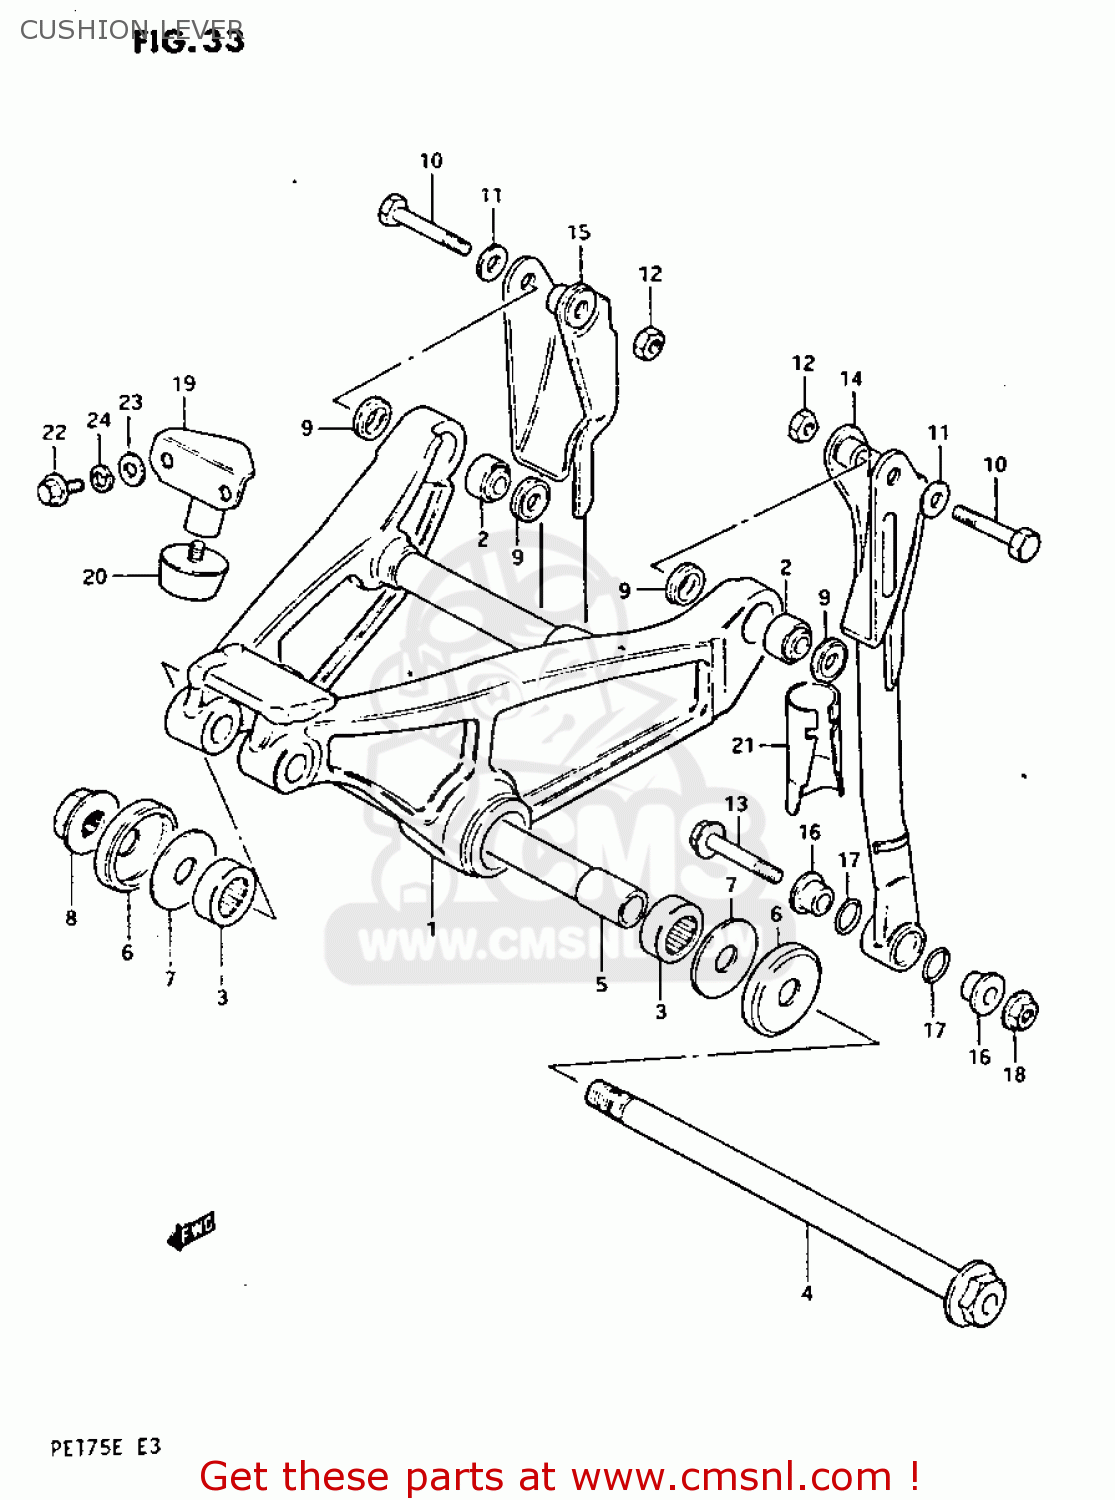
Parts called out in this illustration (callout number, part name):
1	LEVER SET,REAR CUSHION
2	BEARING(8X18X11)
3	BEARING(17X26X20)
4	SHAFT,REAR CUSHION LEVER
5	SPACER,REAR CUSHION LEVER
6	DUST SEAL,REAR CUSHION,LEFT
7	WASHER
8	NUT 12MM
9	DUST SEAL,RR CUSHION LOD UPR.
10	BOLT 8X38
11	WASHER
12	NUT
13	BOLT(8X45)
14	ROD,REAR CUSHION LEVER,LEFT
15	ROD,REAR CUSHION LEVER,RIGHT
16	SPACER,RR CUSHION ROD LWR
17	DUST SEAL,RR CUSHION LOD LWR
18	NUT
19	STOPPER,TENSION
20	RUBBER,TENSION STOPPER
21	PROTECTOR,REAR CUSHION R
22	BOLT
23	WASHER
24	WASHER,LOCK
